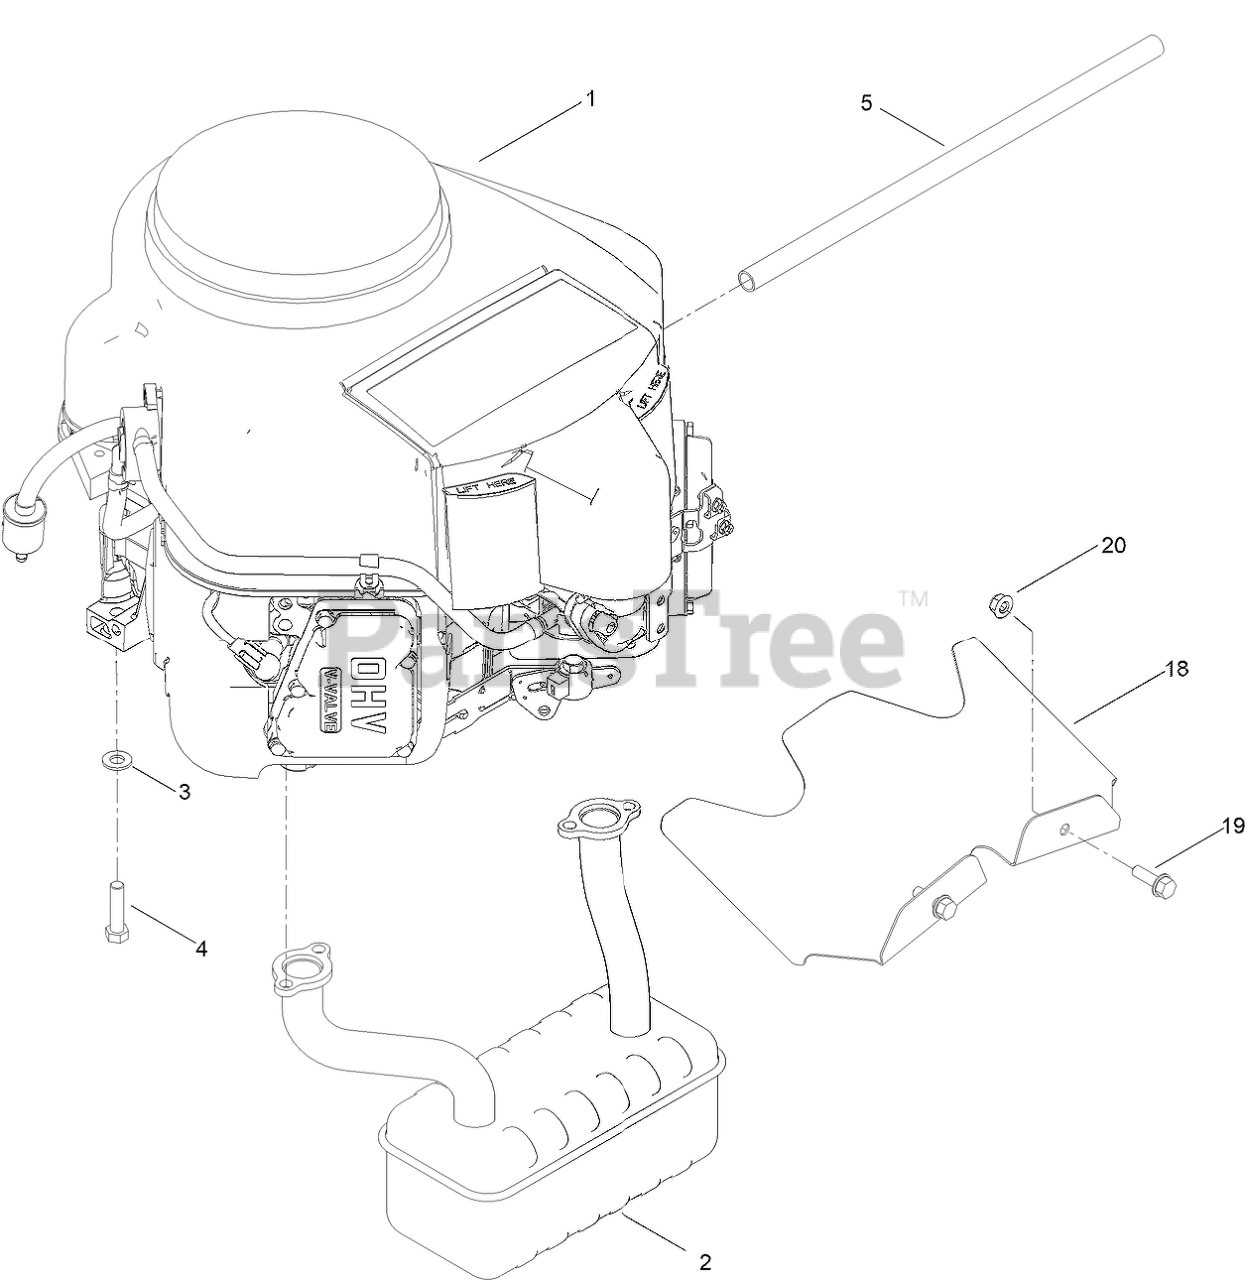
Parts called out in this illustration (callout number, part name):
2	MUFFLER
3	WASHER-FLAT
4	BOLT-HH
5	TUBE-DRAIN, OIL
18	SHIELD-HEAT
19	SCREW-HHF
20	NUT-HF, NI
